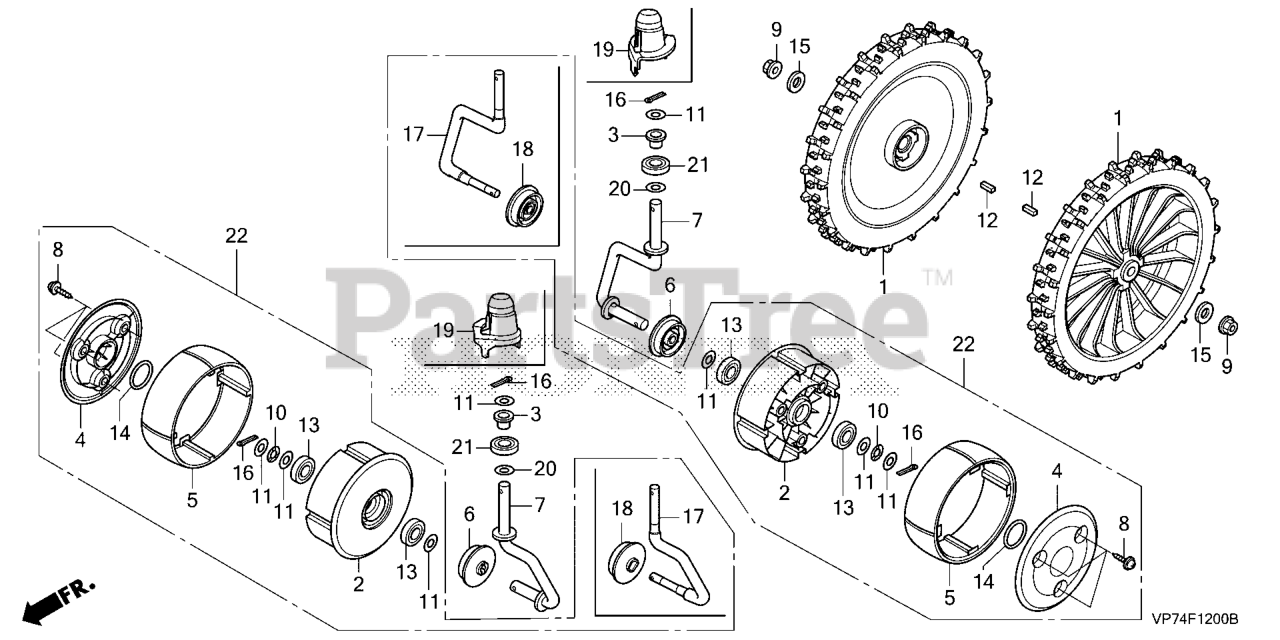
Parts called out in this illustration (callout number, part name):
1	WHEEL COMP, RR.
2	CASTER, FR.
3	BUSH, FR. CASTER
4	COVER, CASTER
5	TIRE, CASTER
8	SCREW, TAPPING (5X16)
9	NUT, SELF-LOCK (6MM)
10	WASHER, WAVE (6MM)
11	WASHER, THRUST (6.2X14X1)
12	KEY FLAT (4X4X14)
13	BEARING (6X17X6)
14	O-RING, FR. CASTER
15	WASHER, PLAIN (6MM)
16	PIN, COTTER (1.6X12)
17	ROD, FR. CASTER
18	CAP, FR. WHEEL
19	CAP, FR. CASTER ROD
21	BEARING (7X17X5)
22	CASTER ASSY.
